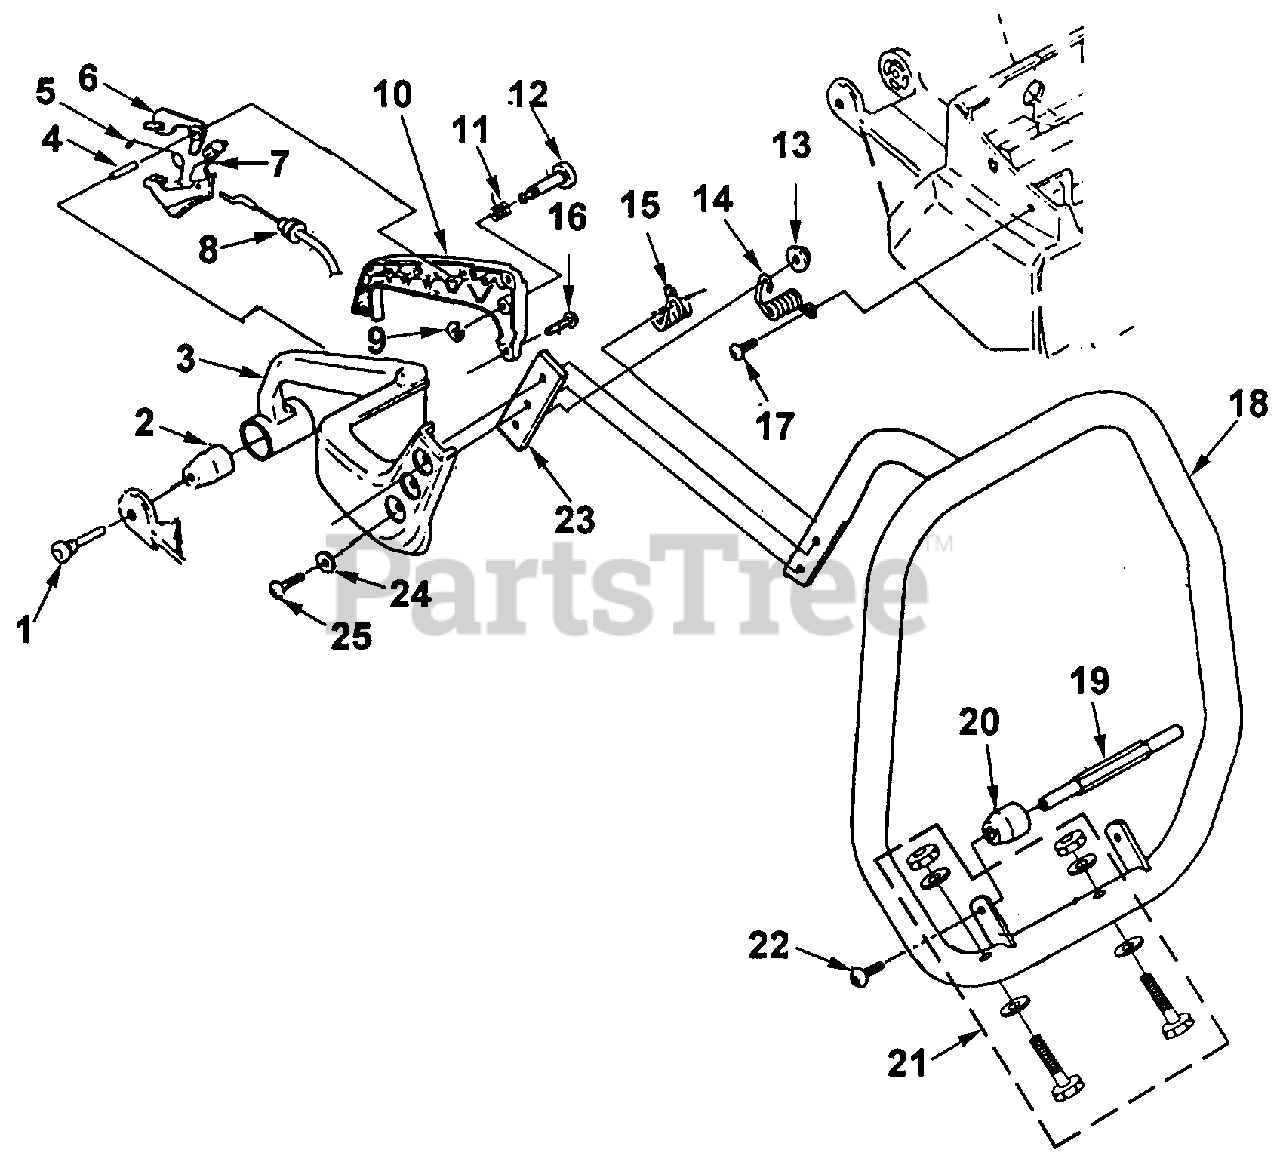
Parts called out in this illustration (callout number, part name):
1	ISOLATOR PIN
2	ISOLATOR-Vibration
3	HANDLE-Rear
4	PIN-Trigger
5	SPRING-Throttle
6	LOCK-Trigger
7	TRIGGER & SWIVEL
8	CABLE-Throttle
9	RING-Retaining
10	COVER-Handle
11	SPRING-Compression
12	PIN-Throttle Lock
13	NUT-Hex (10-24)
14	SPRING-Isolation (Large)
15	SPRING-Isolation (Small)
16	SCREW-Plastite (8-16 x 5/8")
17	SCREW-Torx Hd. (10-24 X 1/2")
18	HANDLE BAR
19	SPACER
20	ISOLATOR-Vibration
21	KIT-Wear Pad
22	SCREW-Torx Hd. (10-24 x 1/2")
23	STRAP, Reinforcing
24	WASHER (#12-11/16)
25	SCREW-Truss Hd. (10-24 x 3/4")
